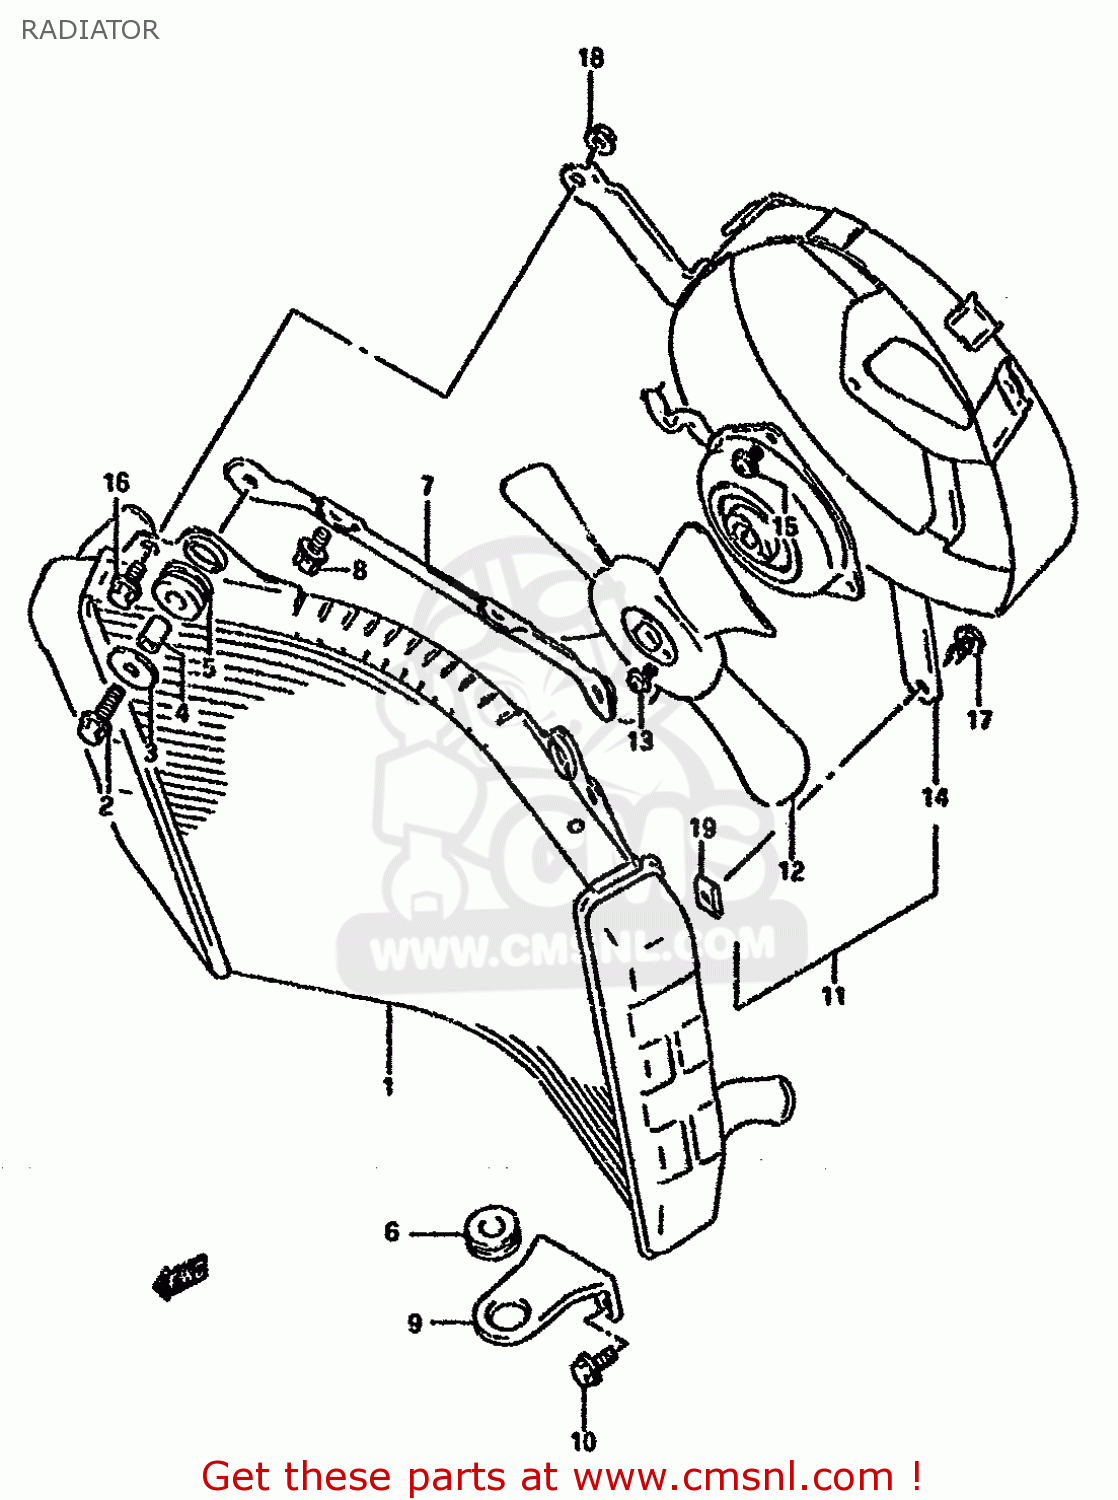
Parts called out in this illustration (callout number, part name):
1	RADIATOR ASSY,WATER
2	BOLT
3	WASHER
4	SPACER(6.5X10.5X12)
5	CUSHION,RADIATOR LWR
6	CUSHION
7	BRACKET COMP,RADIATOR
8	BOLT
9	BRACKET,RADIATOR,LOWER
10	BOLT
11	FAN ASSEMBLY,RADIATOR
12	FAN
13	SCREW 4X6
14	SHROUD
15	SCREW
16	BOLT
17	BOLT
18	NUT
19	NUT,RADIATOR COVER
